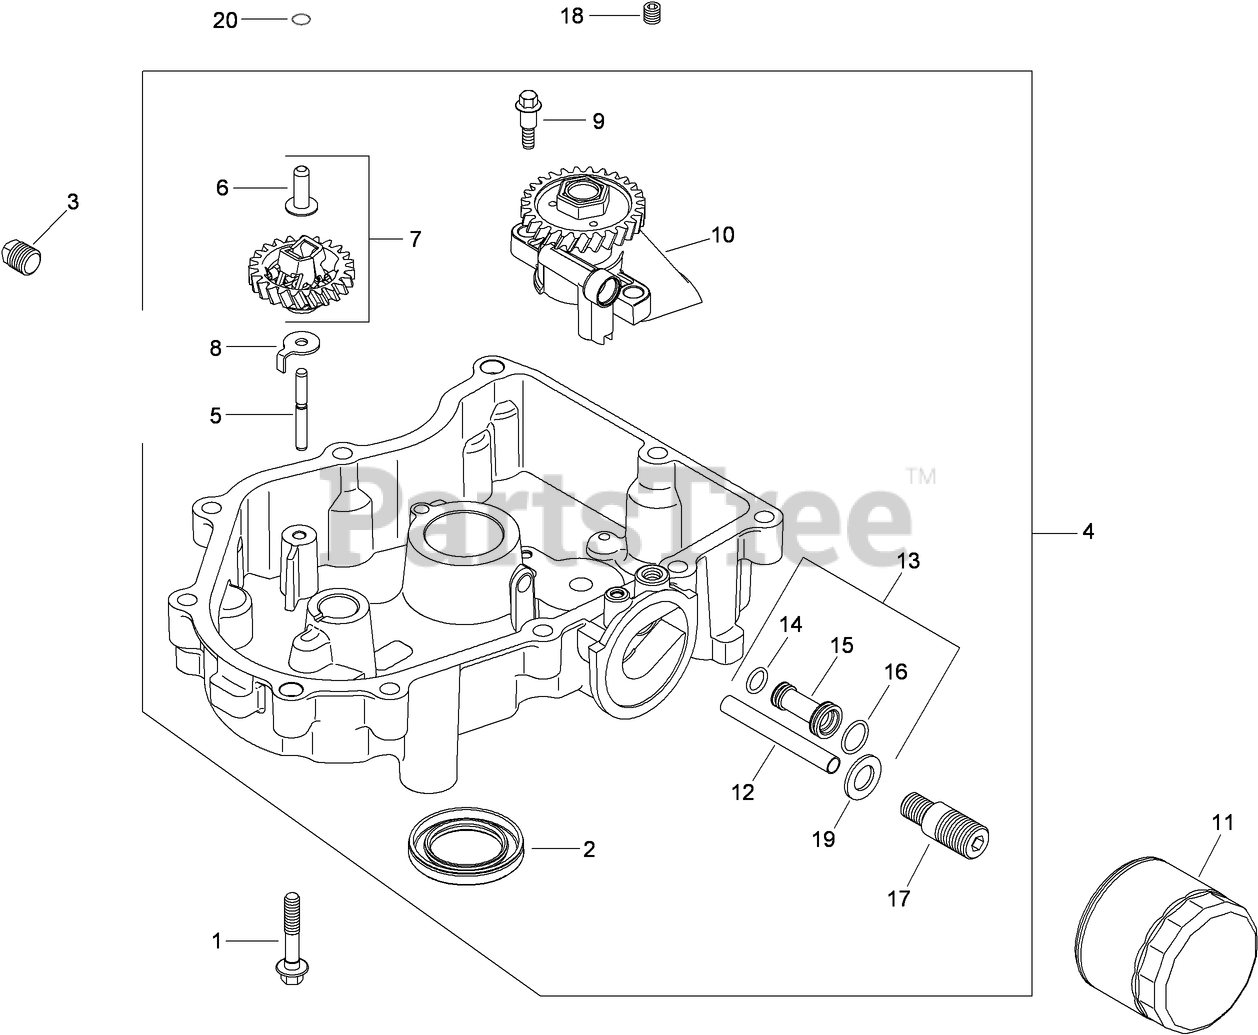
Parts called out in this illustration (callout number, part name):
1	SCREW-FLANGE (M8X1.25X45)
2	SEAL-OIL
3	PLUG-PIPE, SQ HD (3/8)
4	GOVERNOR GEAR W/PIN KIT (INCLUDES REF 2-10, 15-19)
5	SHAFT-GEAR, GOVERNOR
6	PIN-REGULATING, GOVERNOR
7	GOVERNOR GEAR KIT W/PIN (INCLUDES 5)
8	TAB-LOCKING
9	SCREW-SHOULDER, THD FRM (M6x1.0x26.5)
10	OIL PUMP ASM
11	FILTER-OIL
12	TUBE-FEED, OIL (FILTER TO PAN)
13	OIL FEED TUBE ASM (INCLUDES REF 10, 15, 16)
14	O-RING
15	TUBE-FEED, OIL
16	O-RING
17	NIPPLE-FILTER, OIL
18	PLUG-PIPE, COUNTERSUNK (1/8)
19	WASHER-FLAT
20	RETAINER-PIN
